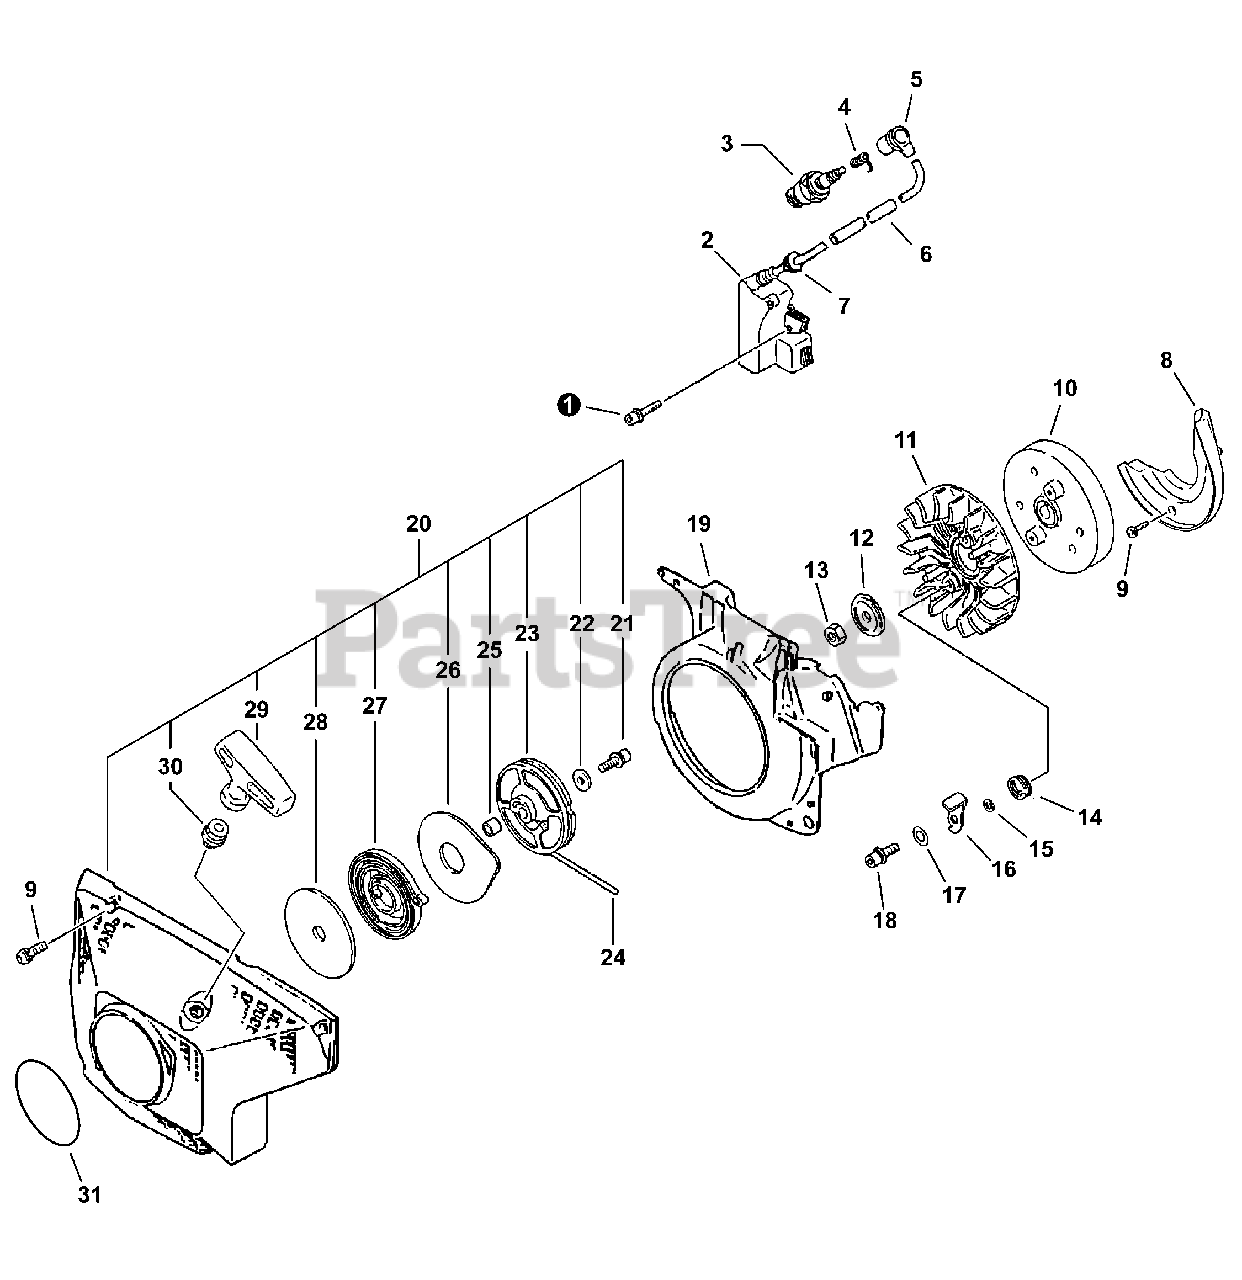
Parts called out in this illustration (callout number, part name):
1	BOLT 4×20
2	COIL, IGNITION
3	PLUG, SPARK -- CJ-6Y
4	TERMINAL, SPARK PLUG CAP
5	CAP, SPARK PLUG
8	PLATE, GUIDE - Gray
8	PLATE, GUIDE - Orange
9	BOLT 5×20
10	FLYWHEEL
11	FAN, COOLING
13	FLANGE NUT 8
14	SPRING, RETURN
15	SPACER, RATCHET
16	PAWL, STARTER
17	WASHER 5
18	BOLT 5×30
19	COVER, FAN - Gray
19	COVER, FAN - Orange
20	STARTER ASY - Gray
20	STARTER ASY - Orange
21	SCREW 5×14
23	DRUM, STARTER
24	ROPE, STARTER - 4mm×900mm
26	PLATE, STARTER
27	SPRING, REWIND
28	PLATE, STARTER
29	GRIP, STARTER
30	GUIDE, ROPE
31	LABEL, ECHO
